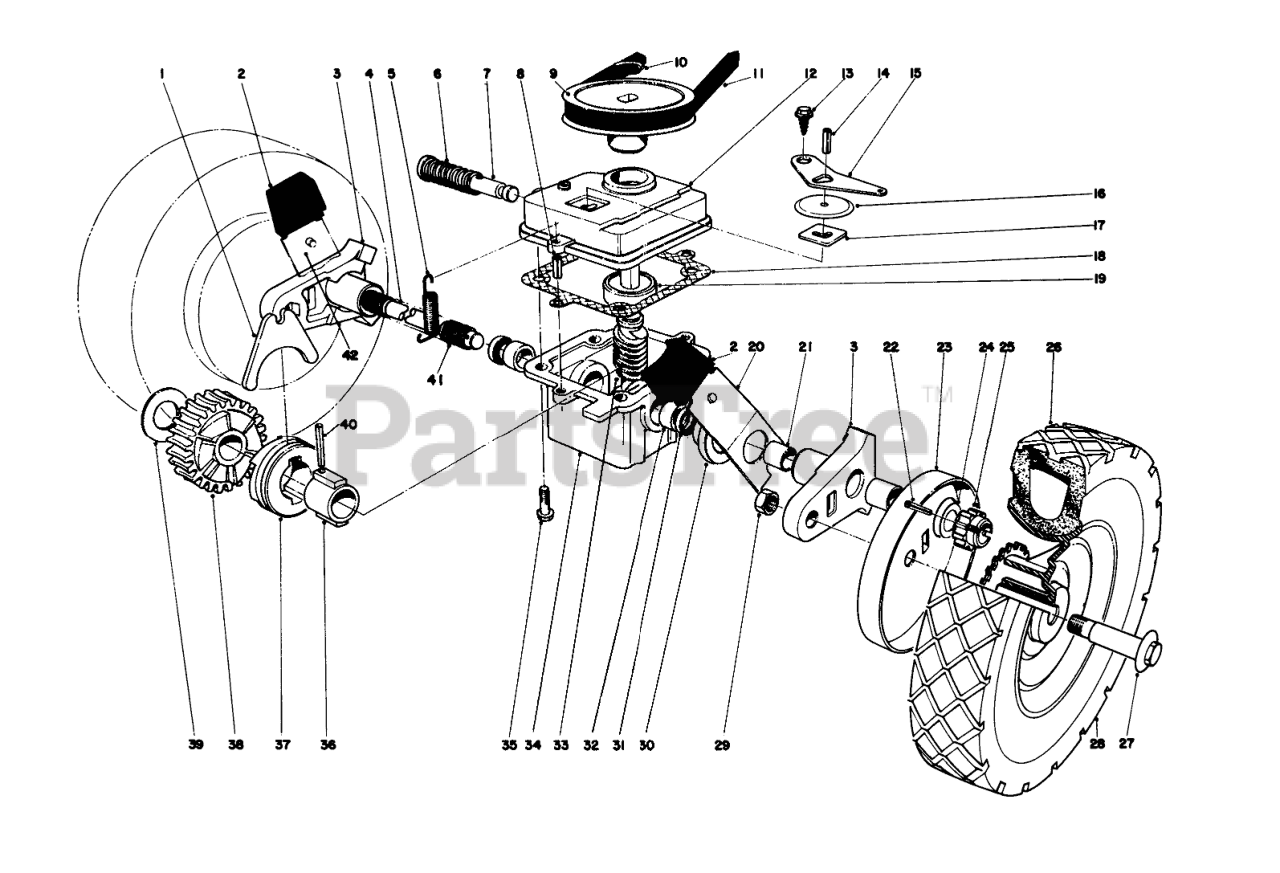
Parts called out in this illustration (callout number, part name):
1	SHIFTER FORK
2	KNOB-ARM
3	Pivot Arm (Incl. Ref. No. 21)
4	Drive Shaft
5	TENSION SPRING
6	SPRING
7	Shift Rod
8	3/16 X 1/2 ROLL PIN
9	PULLEY
10	PUSH-ON 93-3236
11	V BELT
12	GEAR CASE COVER
13	Screw
14	PIN-ROLL
15	SHIFTER ARM
16	TRANS DUST COVER
17	LATCH PLATE
18	GASKET
19	Bearing
20	SPRING ARM ASM SP LH
21	BUSHING
22	PIN-GROOVED
23	WHEEL COVER
24	WASHER-THRUST
25	Pinion
26	WHEEL BUSHING
28	Wheel & Tire (Incl. Ref. No. 26)
29	Nut
30	End Cap
31	Seal
32	Bushing
33	WORM SHAFT
34	Gear Case (Incl. Ref. #31 & 32)
35	Screw
36	SLEEVE
37	CLUTCH JAW
39	THRUST WASHER
40	COIL PIN
41	COVER-SHAFT, DRIVE
42	SPRING ARM ASM SP RH
